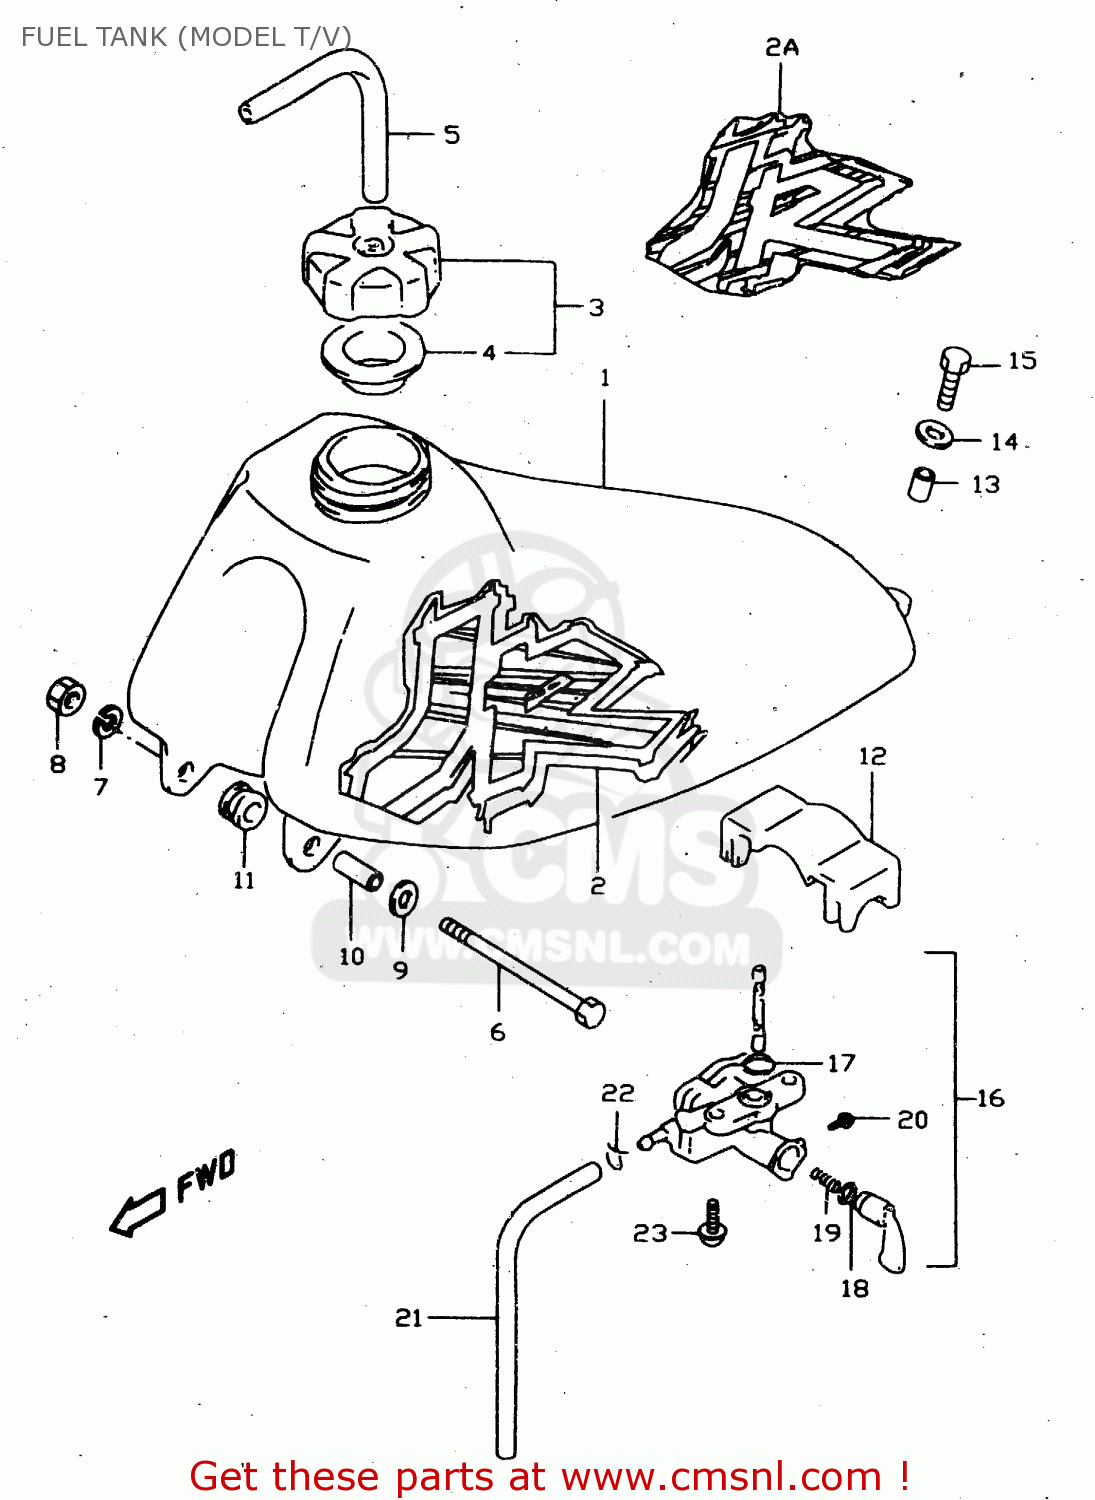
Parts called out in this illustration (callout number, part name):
1	TANK,FUEL
2	EMBLEM SET,FUEL TANK
2A	EMBLEM SET,FRAME TANK
3	CAP,FUEL TANK FILLER
4	GASKET (NAS)
5	HOSE(5X8.2X600)
6	BOLT, FRONT
7	LOCK WASHER
8	NUT 6MM
9	WASHER(6.5X18X1)
10	SPACER (6.8X10X11.5)
11	CUSHION
12	CUSHION,FUEL TANK UPR
13	SPACER(6.5X9X7.2)
14	WASHER(6.5X18X1)
15	BOLT
16	COCK ASSY,FUEL
17	O RING
18	O RING,LEVER
19	SPRING,FUEL COCK VALUE
20	SCREW
21	HOSE(5X8.2X600)
22	CLIP
23	SCREW
